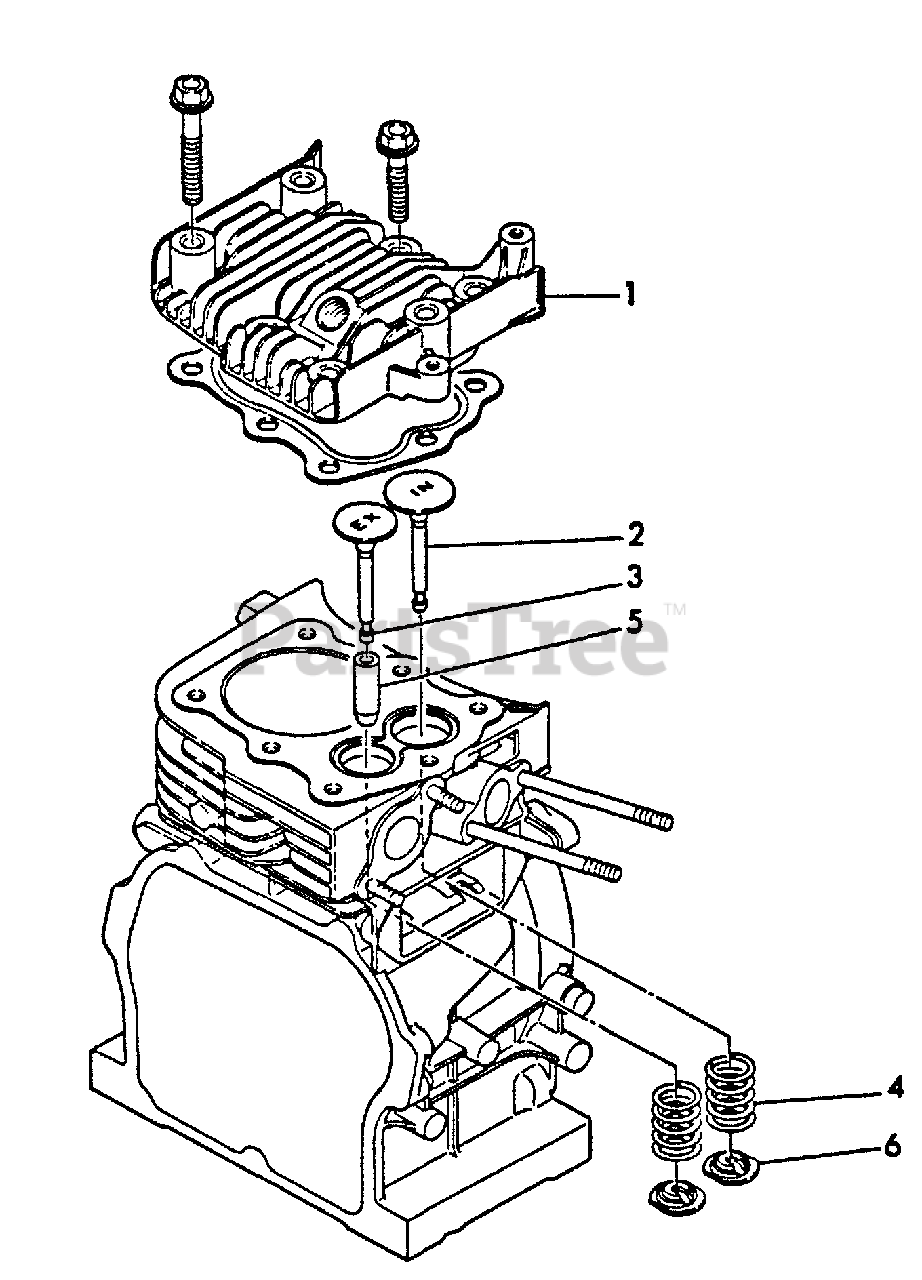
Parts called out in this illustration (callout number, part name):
1	HEAD, CYLINDER
2	VALVE, INTAKE
3	VALVE, EXHAUST
4	SPRING, VALVE
5	GUIDE, VALVE
6	RETAINER, SPRING
